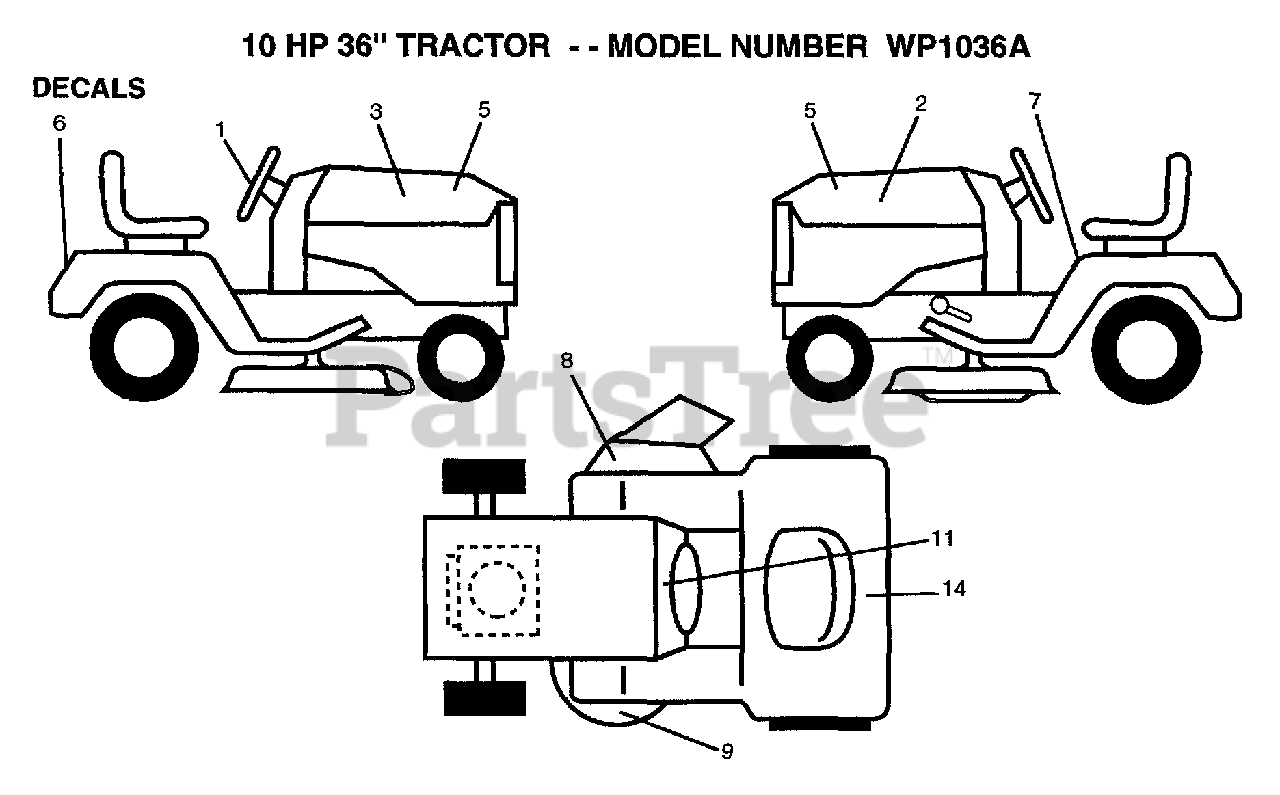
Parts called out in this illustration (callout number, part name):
1	DECAL, WHEEL CAP
6	DECAL, FENDER LOGO
7	DECAL CAUTION
8	DECAL WARING
9	DECAL INSTRUCTION CAUTION
14	DECAL
